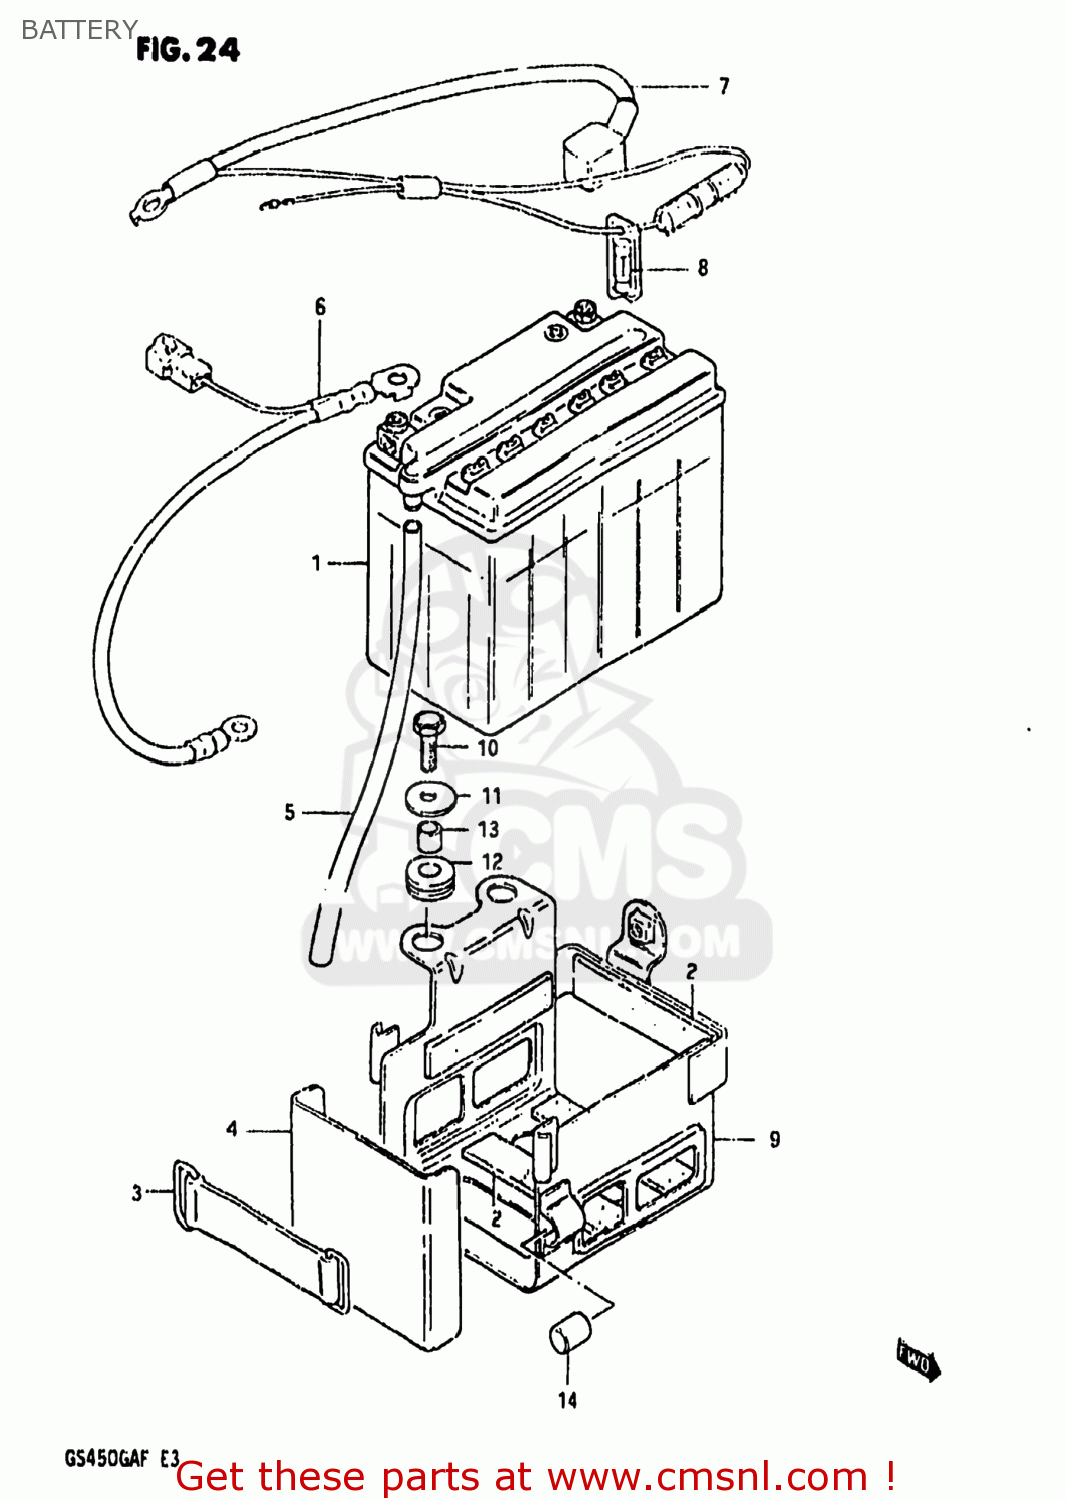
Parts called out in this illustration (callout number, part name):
1	BATTERY ASSEMBLY (12V)
2	PROTECTOR(170X95X3.0)
3	BAND
4	COVER,BATTERY
5	HOSE,BATTERY EXHAUST
6	WIRE,BATTERY MINUS
7	CASE ASSY,FUSE (WITH CABLE)
8	FUSE(15A)
9	HOLDER,BATTERY
10	BOLT,M6X1X20
11	WASHER
12	CUSHION
13	SPACER (6.1X9X9)
14	CUSHION
